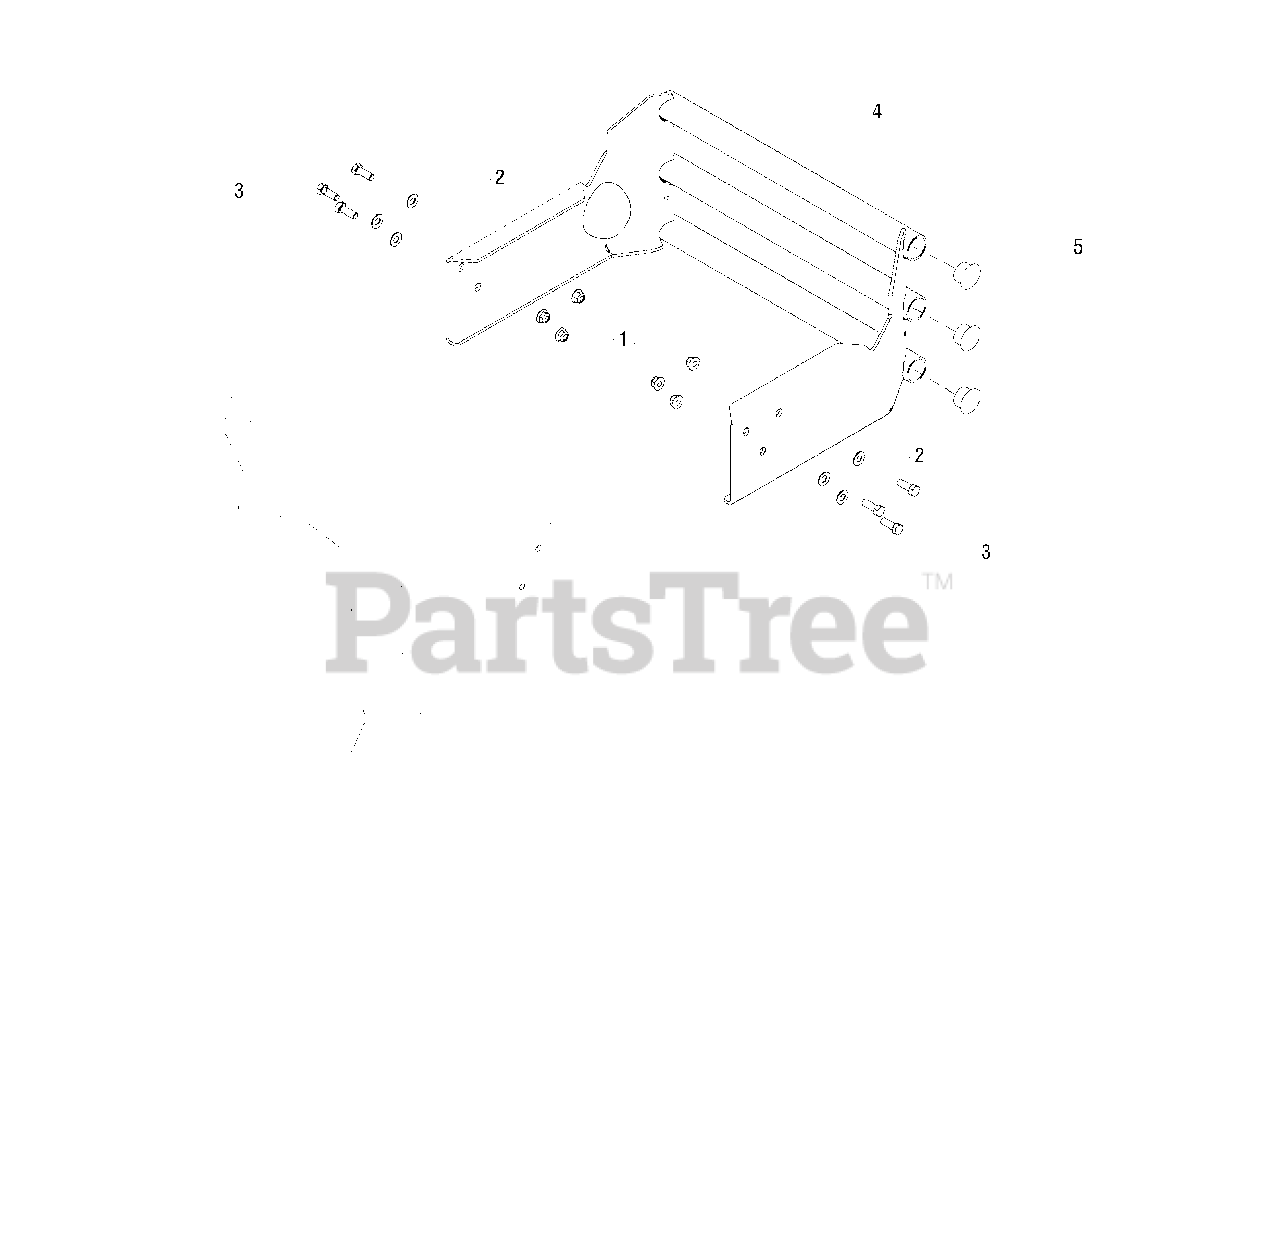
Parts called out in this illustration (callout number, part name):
1	NUT, 3/8-16 HEX NYLOCK FLANGE
2	WASHER, 3/8 SAE
3	BOLT, 3/8-16 X 1" GD5
4	WELD, BUMPER, SNAPPER Z
5	PLUG, PANEL, 1.25 BLACK
